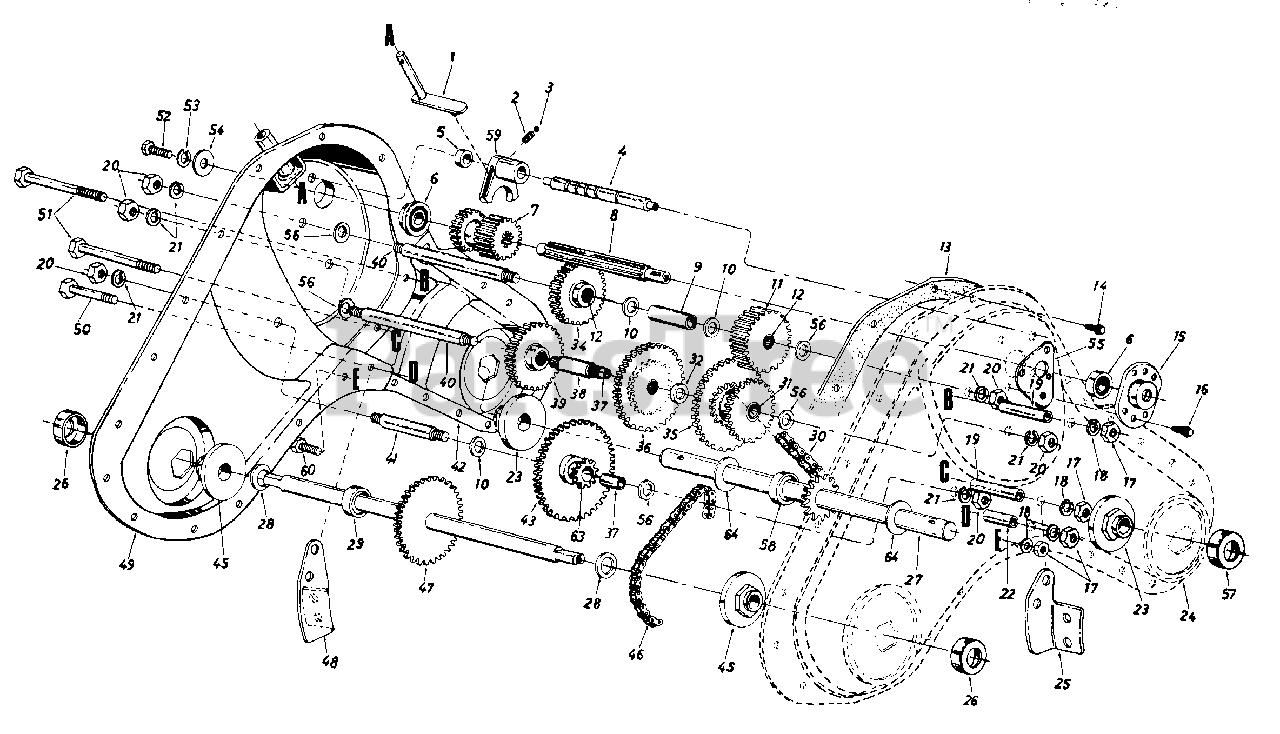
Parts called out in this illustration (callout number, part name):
1	Shifting Bracket Ass'y.
2	Compression Spring .50" Lg.
3	Ball Detent .250" Dia.
4	Detent Shaft 1/2n Dia.
5	Spacer .505" I.D. x .88" O.D.
6	Ball Brg. .62n I.D. x 1.38"
7	Spur Gear 16T
8	Input Spline Shaft 7/8"
9	Spacer 557" I.D. x 2.85" Lg.
10	Fl-Wash. 640" I.D. x 1.24"
11	Spur Gear 30T 7/8" I.D.
12	Needle Bearing 5/8" I.D.
13	Gasket-Trans. Hsg.
14	Hex Wash. S-Tap Scr. 1/4-20 x 50" Lg
15	1-3/8n Dia. Bearing Housing
16	Hex TT-Tap Scr. 1/4-20 x .75"
17	Hex Nut 5/16-18 Thd.*
18	L-Wash. 5/16" I.D.*
19	Spacer 1.56" Lg.
20	Hex Nut 7/16-20 Thd.
21	Bell-Wash. .45" I.D. x 1.0"
22	Spacer 1.015" Lg.
23	Tine Shaft Brg. 1.002 x 2.50
24	Trans. Housing Ass'y.-L.H.
27	Tine Shaft Ass'y. 1" O.D.
28	Fl-Wash. .75" I.D. x 1.5" O.D.
29	Spacer .75" I.D. x .50" Lg.
30	Chain #50 5/8 Pitch x 52 Links-Endless
31	Needle Bearing 5/8" I.D.
32	Fl-Wash. 5/8" I.D.
34	Spur Gear 30T 12/16n I.D.
35	30/44T Gear Ass'y. Comp.
36	Spur Gear 44T
37	Sleeve Bearing
38	Gear Hub 3/4" I.D. x 3n Lg.
39	Spur Gear 30T 1.on I.D. x 1/2 W
40	Jack Shaft 518" Dia. x 5"
41	Jack Shaft 518" Dia. x 2.38"
45	Wheel Brg. .752" x 2.5"
46	#420 Chain 1/2 Pitch x 50 Links-Endless
47	Wheel Shaft Ass'y. 15.6"
51	Hex Bolt 5/16-18 x 2.5"
52	Hex Bolt 1/4-20 x .62" Lg.
53	L-Wash. 3/8" I.D.
54	Fl-Wash. 1/4" I.D. x .93" O.D.
55	Gear Positioner Bracket
56	Fl-Wash. 7/16n I.D. x 1-3/8"
57	Dust Cover Ass'y. 1" Shaft
58	Spacer 1" I.D. x 2n O.D.
59	Shifting Fork
60	Hex Bolt 5/16-18 x .75n Lg.
63	10T Sprocket Ass'y.
64	Thrust Wash. 1.03" I.D. x 1.62" O.D.
